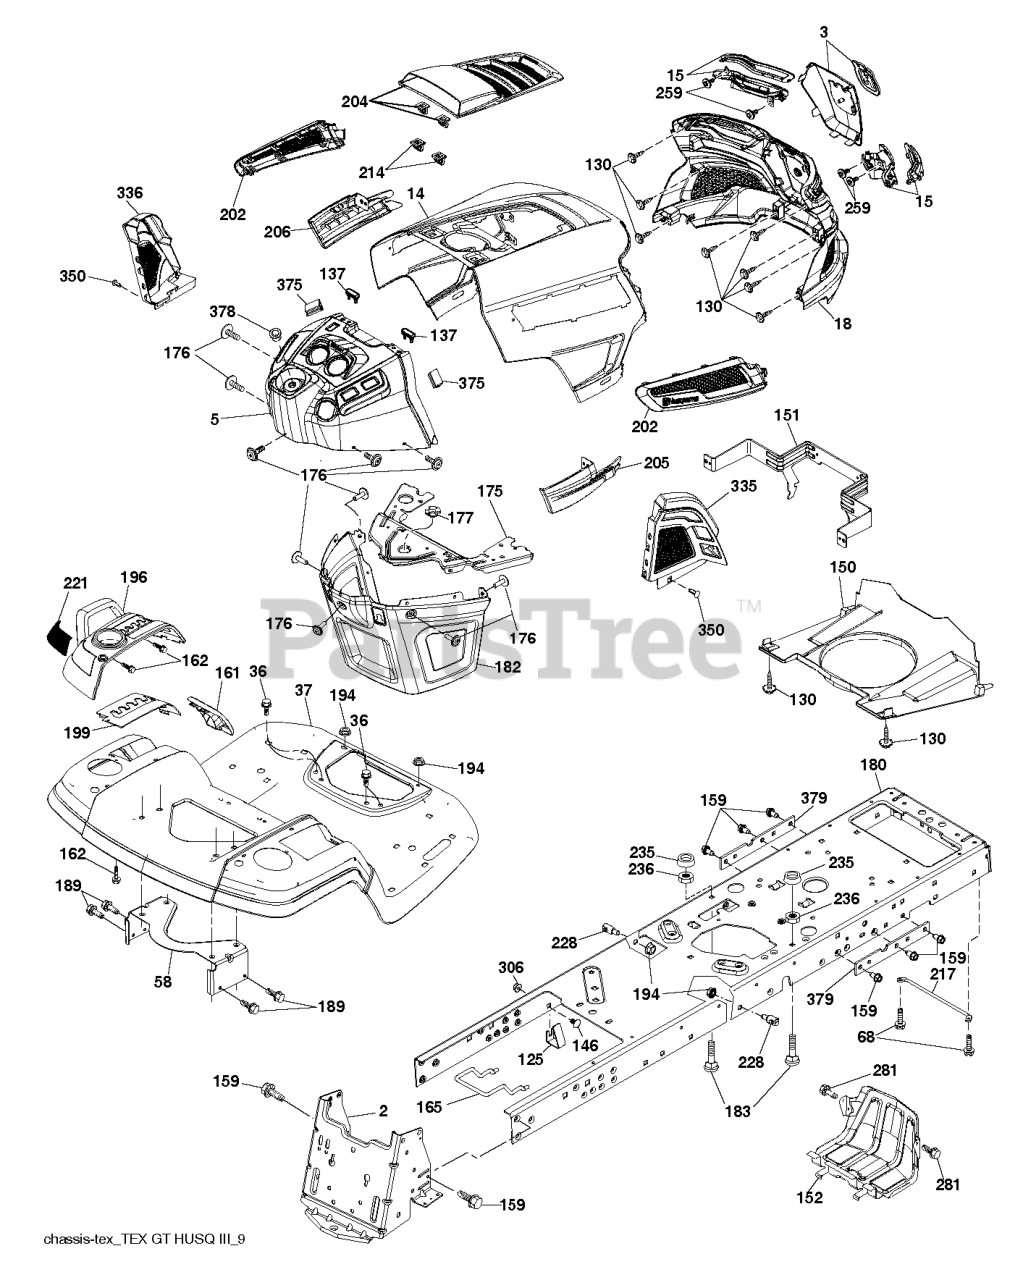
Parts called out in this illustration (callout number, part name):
2	DRAWBAR.STGT
5	DASH.UPR.GT2.DUAL.RD.PT
14	HOOD.ASM.HUSQVARNA.GT.TEX.ORAN
15	Service Kit
36	SCREW 5/16"
37	FENDER.PNT.TX.GT.CH/FW/DL.HUSQ
58	BRKT.SUPPORT.FNDR/TANK
125	CLIP.FUEL.LINE
137	BUMPER DASH
146	BOLT.RDHD.SHT.SQNK.3/8-16X5/8
150	AIR.DUCT.GTV.BLACK
151	BRACKET.PIVOT.HOOD.GT.HUSQ.II
152	SHIELD.BROWNING.PNT.GT.V2
159	SCREW, 3/8-16X3/4
161	CONSOLE.WINDOW.FUEL.HUSQ.GT
165	SUPPORT.TANK.REAR.B/TE
175	PLATE.PNT.CROSSMEMBER.HUSQ/PRE
176	SCREW.#10-24X5/8.RN.QU
177	BUSHING STEERING
180	CHASSIS.LT/GT.BOLTED
182	DASH.LOWER.COMMON.12V.ADAPTOR
189	SCREW
196	SUBASM.CONSOLE.HUSQ.GT.DECKLFT
199	PLATE.DECK.LIFT.HUSQVARNA.GT
202	Vents
204	Vents
205	SIDE.TRIM.RH.GT.HUSQ.II
206	SIDE.TRIM.LH.GT.HUSQ.II.GRAY
214	CLIP.RETAINER.TINNER.
217	ROD.PIVOT.HOOD
221	REFLECTOR.LH.TEX GT HU
228	STUD.FASTNER.W/ANTI-ROTATE
236	NUT.CENTERLOCK.5/16-
281	SCREW 3/8-16X1
306	NUT LOCK FLG 3/8-16 UNC
335	COVER.LOWER.DASH.RH.BLACK
336	COVER-LH.LOWER.DASH.GT2.BLACK
350	CLIP.X-MAS.TREE
375	BUMPER CLIP-ON. DASH 1"
378	BUSHING FLANGE; PLASTIC
379	CHASSIS.PLATE.REINFORCEMNT.431
